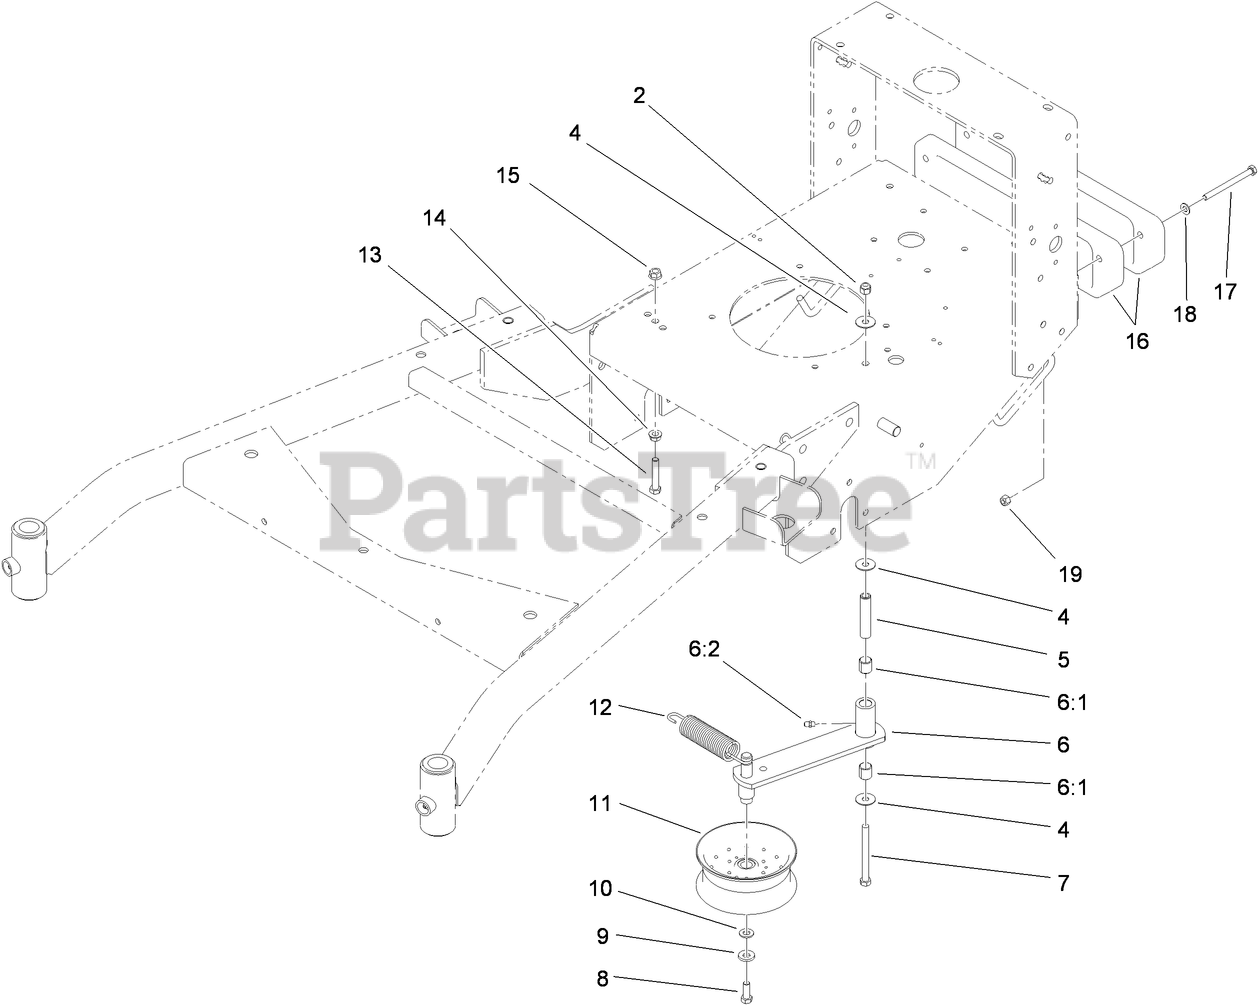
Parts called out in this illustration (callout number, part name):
2	NUT-LOCK, NI
4	WASHER
5	TUBE-IDLER
6	IDLER ARM ASM
6:1	SLEEVE-BEARING
6:2	FITTING-GREASE
7	SCREW-HH
8	SCREW-HH
9	WASHER-BELLEVILLE
10	WASHER-FLAT
11	PULLEY-IDLER
12	SPRING-EXTENSION
13	SCREW-HH
14	NUT-HHF, WHIZ
15	NUT-HF
16	WEIGHT-CAST
17	SCREW-HH
18	WASHER-PLAIN
19	NUT-LOCK, NI
